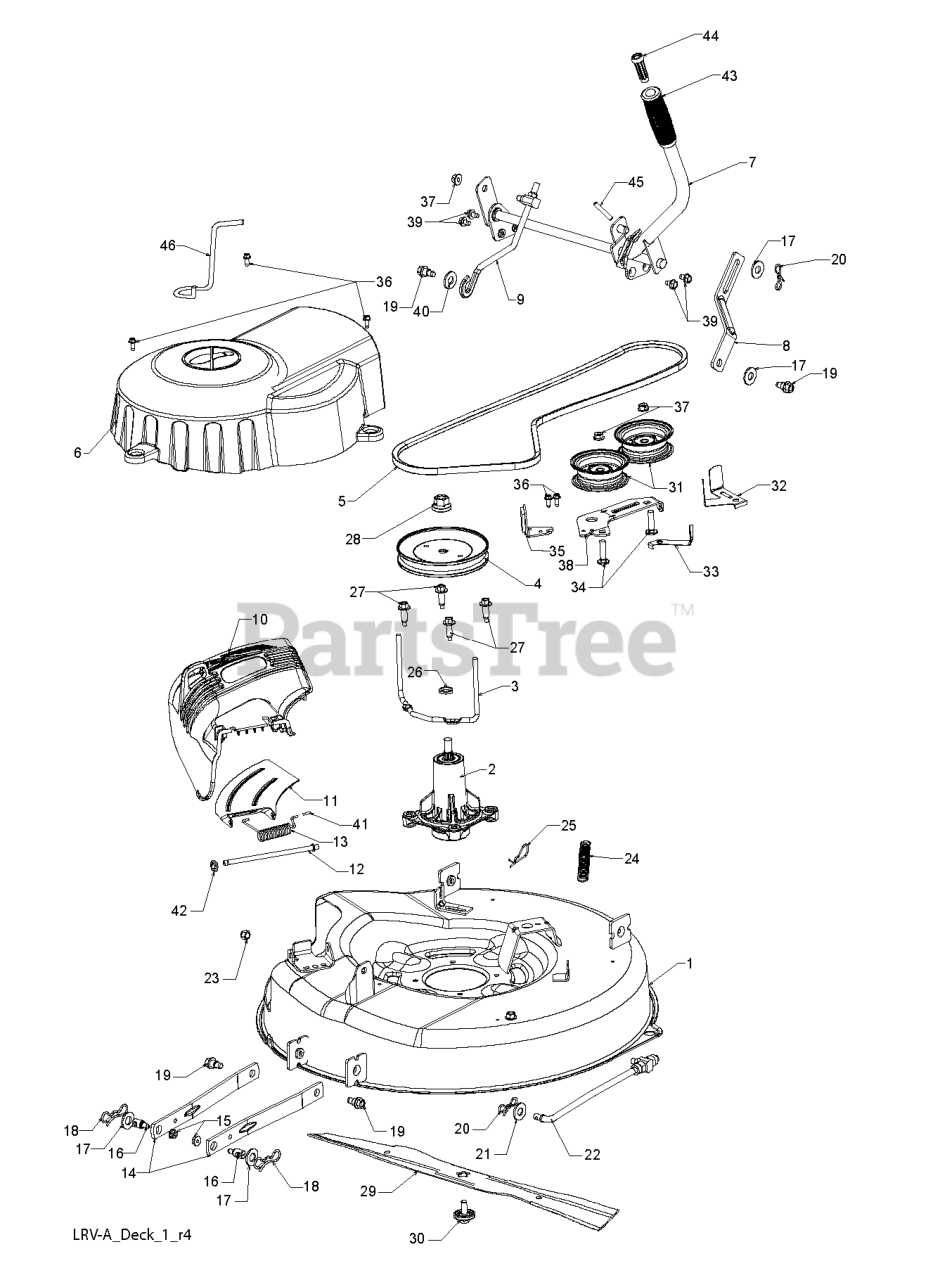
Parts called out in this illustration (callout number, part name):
1	DECK.WELDMENT.26'LRV.BLACK
2	MANDREL.ASM.SUB-NON.GR
3	KEEPER.BELT.MANDREL.PULLEY
4	PULLEY.MANDREL
6	COVER, MANDREL
7	LIFT.ASM.DECK.LRV
8	LINK, DECK LIFT
9	LINK.ASM.LIFT.ADJUSTABLE
10	DEFLECTOR DEFLECTOR.LRV.26
11	SUPPORT, DEFLECTOR
12	ROD.HINGE
13	SPRING.TORSION.DEFLECT
14	ARMS.SUSP.MOWER.REAR.SRD
15	NUT LOCK HEX FLANGE 5/16-18
16	STUD.FASTNER.W/ANTI-ROTATE
17	WASHER.CLEAR.ZINC
18	PIN.COTTER.7/16.BOW TI.
19	BOLT.SHOULDER
20	PIN.COTTER.5/16.BOW TI
22	LINK.ASM.TOP.DECK.LRV
23	LOCKNUT
24	SPRING.EXTENSION.DECK.LRV
25	RETAINER M
26	WASHER.SPACER.MANDREL
27	SCREW, WASHER HEAD
28	NUT.FLANGE.LOCK.TOP
30	BOLT.WASHER.ASM.7/16-2
31	PULLEY.IDLER.48"PRIMARY
32	GUARD, BELT
33	KEEPER BELT
34	BOLT.3/8-16X1.50
35	RP ARM.BRAKE.MOWER.38"LH.TEX
36	SCREW.1/4-20X5/8
37	NUT LOCK FLG 3/8-16 UNC
38	ARM, IDLER
39	Screw 5/16-18 x 1/2 Hex, Self Tapping 5/16-18 x 1/2
40	WASHER
41	CAP-SLEEVE LT
42	NUT PUSH M
43	GRIP HANDLE
44	PLUNGER.ASM.LRV
45	PIN GROOVE.
46	KEEPER.BELT
